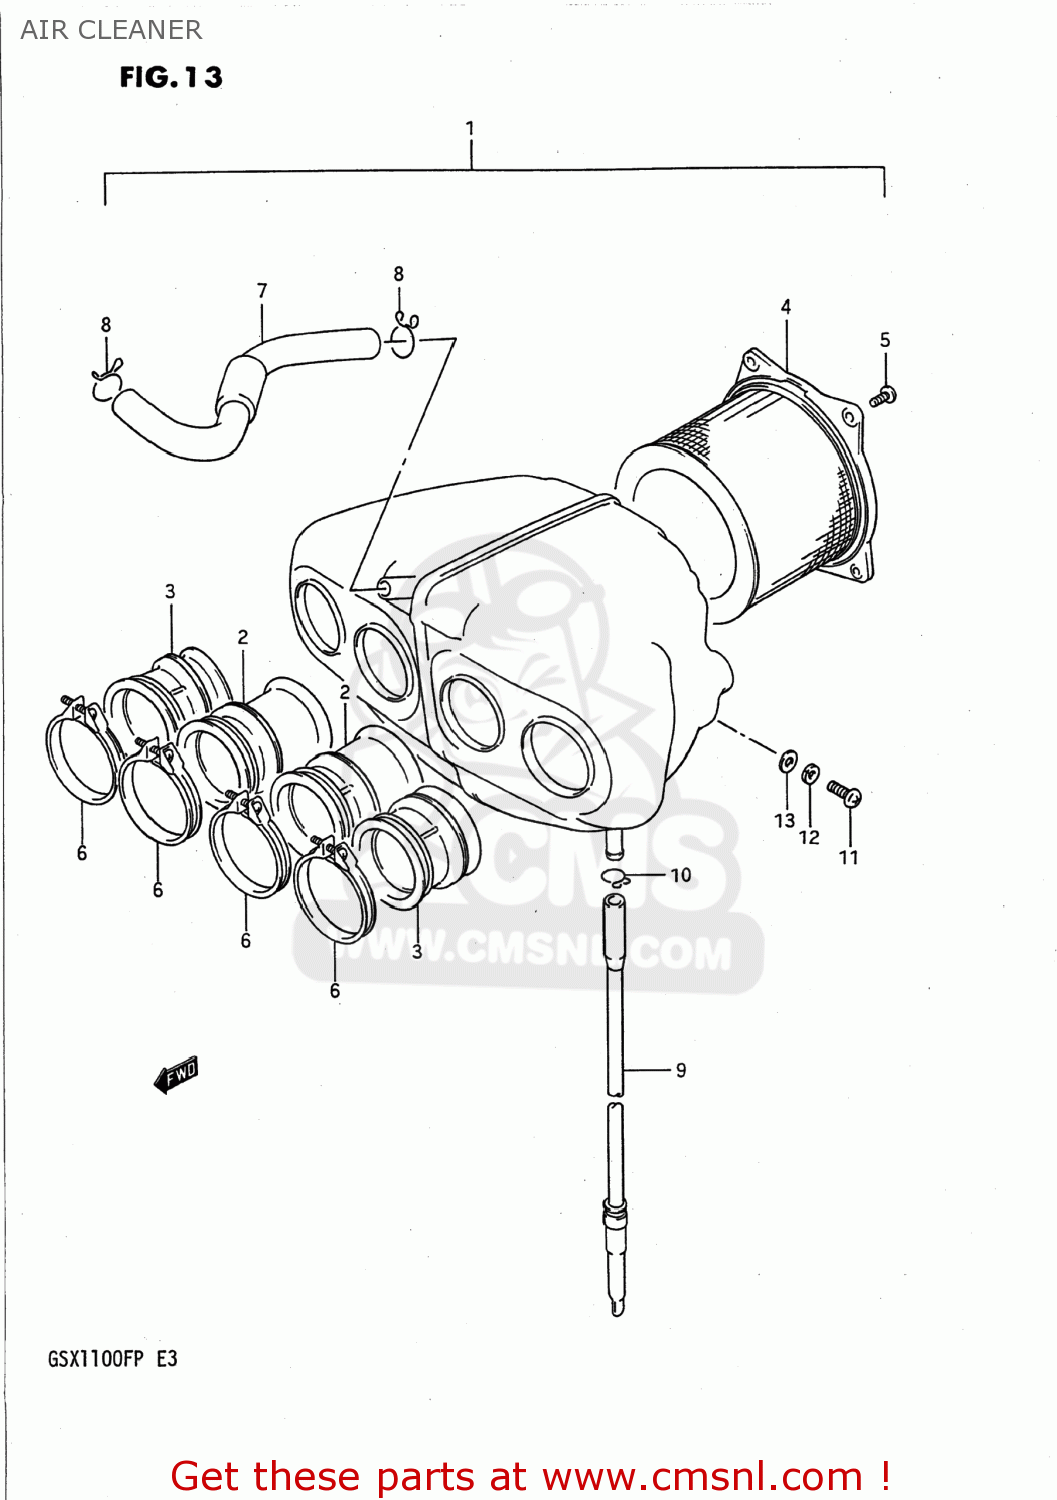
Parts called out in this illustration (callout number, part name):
1	CLEANER ASSEMBLY,AIR
2	TUBE,OUTLET NO.1
3	TUBE,OUTLET NO.2
4	FILTER,AIR CLEANER
5	SCREW, FRONT & REAR
6	CLAMP
7	TUBE,BREATHER
8	CLIP
9	DRAIN TUBE
10	CLIP
11	SCREW
12	WASHER,LOCK
13	WASHER
